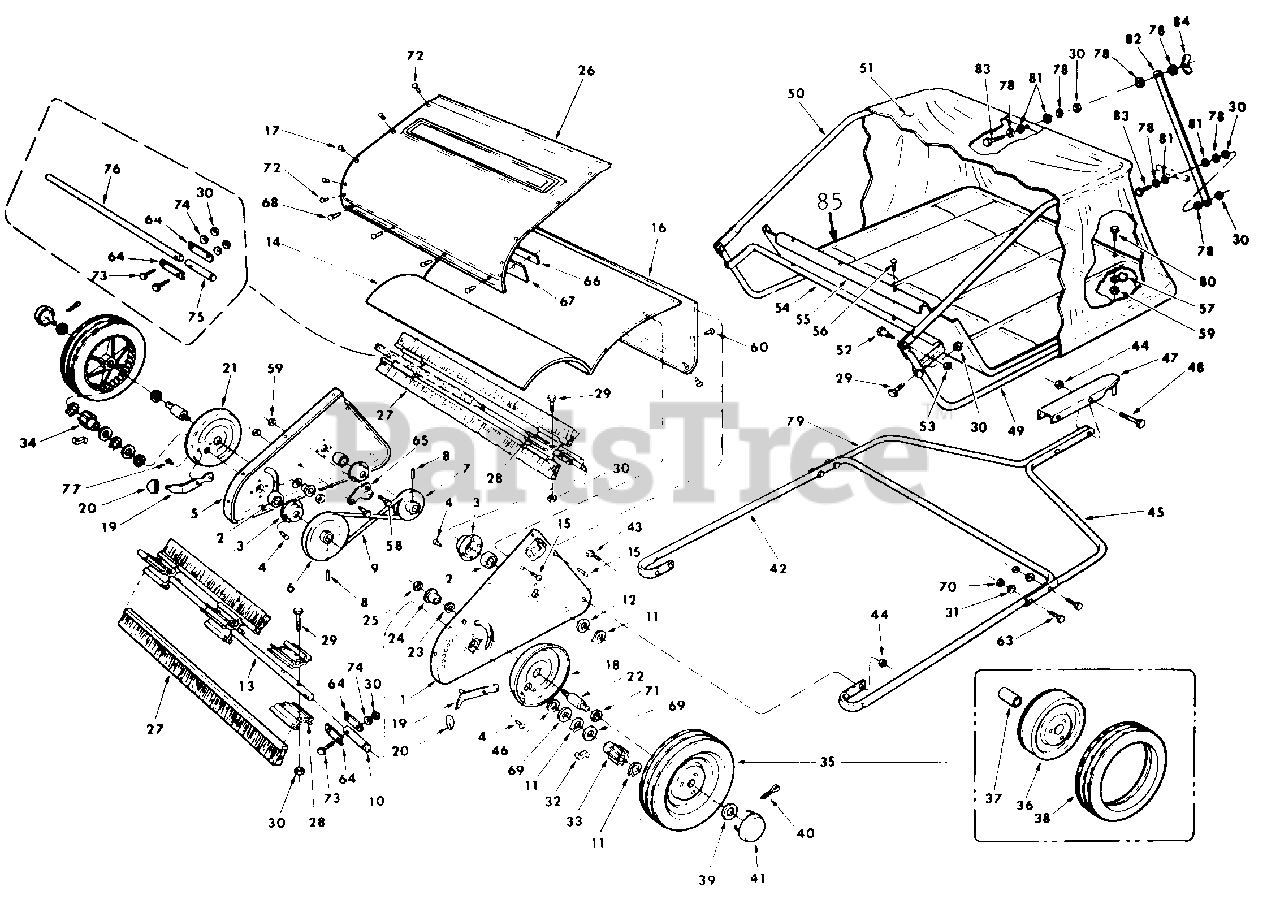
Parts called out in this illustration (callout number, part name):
1	Assembly End Plate R.H.
2	Bearing
3	Retainer Beari ng
4	Rivet (3/16 Dia. x 5/16)
5	Assembly End Plate L.H.
6	Assembly Pulley
7	Pul ley
8	Rollpin (.156 Dia. x 11/4)
9	Belt (3/8 Round Sect.)
10	Shaft Brush Drive
11	Ring Retainer
12	Washer Flat (5/8 x 15/16 x 1 /16)
13	Shaft Brush Drive
14	Baffle Top
15	Screw (10-32 x 1-1/8 Sems)
16	Baffle Front
17	Screw (10-32 x 3/8 Sems)
18	Assembly Dust Cover R.H.
19	Assembly Wheel Adj. Lever
20	Knob Wheel Adj.
21	Assembly Dust Cover L.H.
22	Axle Wheel
23	Washer Bowed
24	Bushing Spacer
25	Nut Hex
26	Cover Sweeper
27	Ass'y. Brush and Channel
28	Assemblv Brush Retainer
29	Bolt (1/4-20 x 1-1/8 Hex Hd.)
30	Nut (1/4-20 Hex Lock)
31	Washer Lock (5/16 Split)
32	Pawl
33	Pinion R.H.
34	Pinion L.H.
35	Assembly Wheel
36	Wheel Gear & Rim
37	Bushing
39	Washer (3/8 x 7/8 x 3/16)
40	Cotter Pin (1/8 x 5/8)
41	Cap Hub
42	Draw Bar Rear
43	Bolt (5/16-18 x 3/4 Sem Hex)
44	Nut (5/16-18 Hex Lock)
45	Draw Bar Front
46	Washer Bowed
47	Ass'y. Bracket & Pin
48	Bolt (5/16-18 x 2-5/8 Hex Hd.)
49	Frame Catcher Lower
50	Frame Catcher Upper
51	Basket Fabric
52	Bolt Shoulder
53	Nut (3/8-16 Hex Lock)
54	Brace Frame
55	Panel Catcher Bottom
56	Screw (10-32 x 1/2 Phillips)
57	Clamp
58	Bolt (10-32 x 3/8 Truss Hd.)
59	Nut (10-32 Hex Lock)
60	Screw (10-32 x 3/8 Sems)
63	Bolt (5/16 x 1-3/8 Special)
64	Coupling Half
65	Scraper Impeller Pulley
66	Retainer Skirt
67	Skirt
68	Screw (10-32 x 3/8 Phillips Hd.)
69	Washer (.59 x 1-1/8 x .015)
70	Nut (5/16-18 Hex)
71	Washer (.78 x 1-1/4 x .015)
72	Screw (10-12 x 5/8 Sheet Metal)
73	Bolt (1/4-20 x 11/4 Hex Hd.)
74	Lockwasher (1/4 Std. Split)
75	Shaft Impeller
76	Shaft Impeller
77	Rivet (3/16 Dia. x 1/4 Truss Hd.)
78	Washer (17/64 x 3/4 x 1/16)
79	Draw & Bar Front
80	Bolt (10-32 x 3/8 Hex Hd.)
81	Washer (21/64 x 3/4 x 3/32 Nylon)
82	Support
83	Bolt (1/4-20 x 13/4 Hex Hd.)
84	Nut (1/4-20 Wing-Lock)
85	Vinyl Strip Edge 96" Lg.
